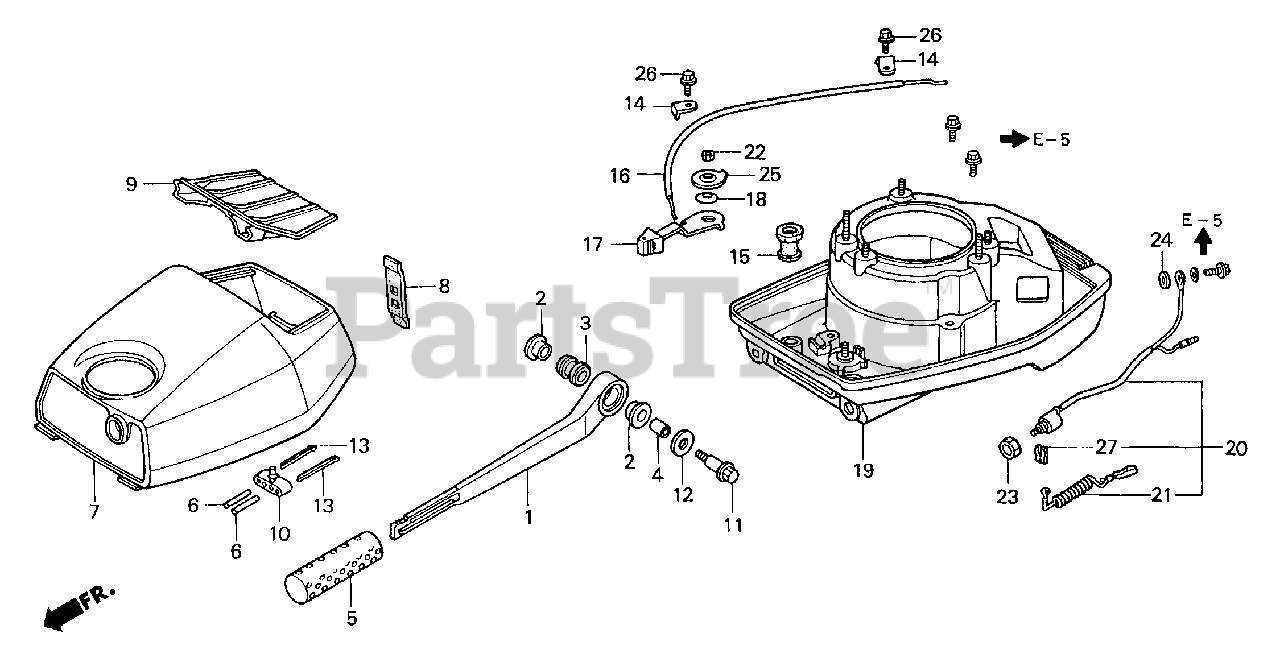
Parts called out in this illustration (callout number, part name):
1	HANDLEBAR *NH210MC* (AQUA SILVER METALLIC-C)
2	COLLAR, HANDLE MOUNTING
3	RUBBER, HANDLE MOUNTING
4	COLLAR, DISTANCE
5	GRIP, LEVER
6	PIN, SHEAR
7	COVER, ENGINE *NH209* (MARINE WHITE)
8	BELT, ENGINE COVER
9	COVER, TOP
10	HOLDER, PARTS
11	BOLT, FLANGE (8X40)
12	WASHER (12.5X32)
13	PIN, COTTER (3MM)
